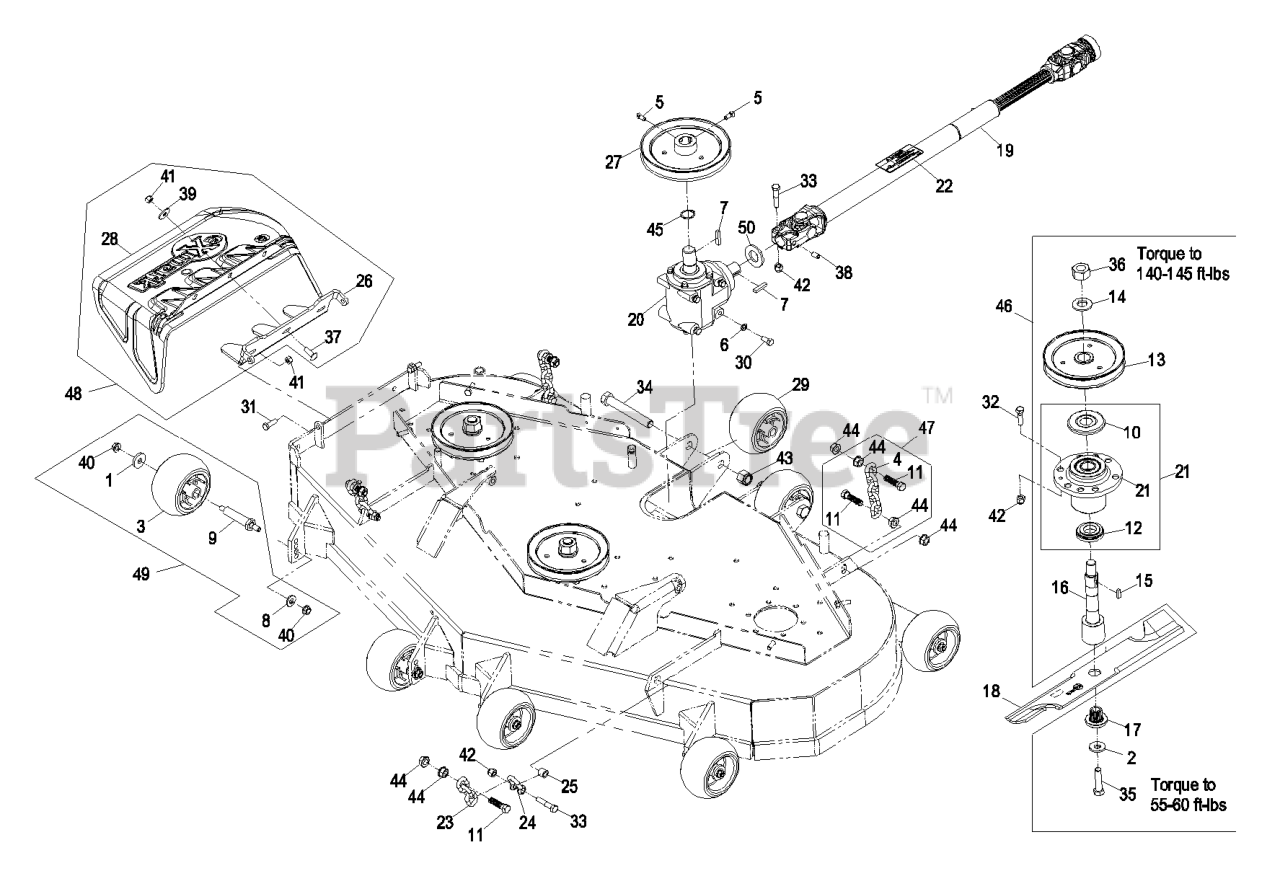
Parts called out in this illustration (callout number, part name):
2	WASHER-SPRING
3	ROLLER-SCALP, ANTI
4	CHAIN-LIFT, DECK
5	SCREW-SET
6	WASHER-LOCK
7	KEY-SQUARE
8	WASHER-BELLEVILLE
10	GUARD-BEARING, TOP
11	SCREW-HH
12	SPACER-GUARD, BOTTOM
13	SHEAVE,BLADE DRIVE 6.30
16	KIT, SPLINED SPINDLE 103-
17	BUSHING,SPLINED
20	GEARBOX,90 DEGREES
21	KIT, CUTTER HOUSING
22	DECAL-DRIVELINE
23	CHAIN-DECKLIFT
24	SHACKLE,FRONT CHAIN
25	BUSHING,SHACKLE
26	BRACKET,DISCHARGE CHUTE
27	SHEAVE,6.88 ED B-SEC
28	CHUTE,DISCHARGE
29	ROLLER, FULL HUB
30	SCREW-HH
31	SCREW-HH
32	SCREW-HH
33	SCREW-HH
34	SCREW-HH
35	SCREW-HH
36	NUT-HH
37	SCREW-CARR
38	SCREW-SET
39	WASHER-FLAT
40	NUT-HHF, WHIZ
41	NUT-LOCK, NI
42	NUT-LOCK, NI
43	NUT-LOCK, NI
45	RING-RETAINING
46	ASM, CUTTER HSG COMPLETE
47	DECK CHAIN ASM
50	WASHER,SPECIAL
